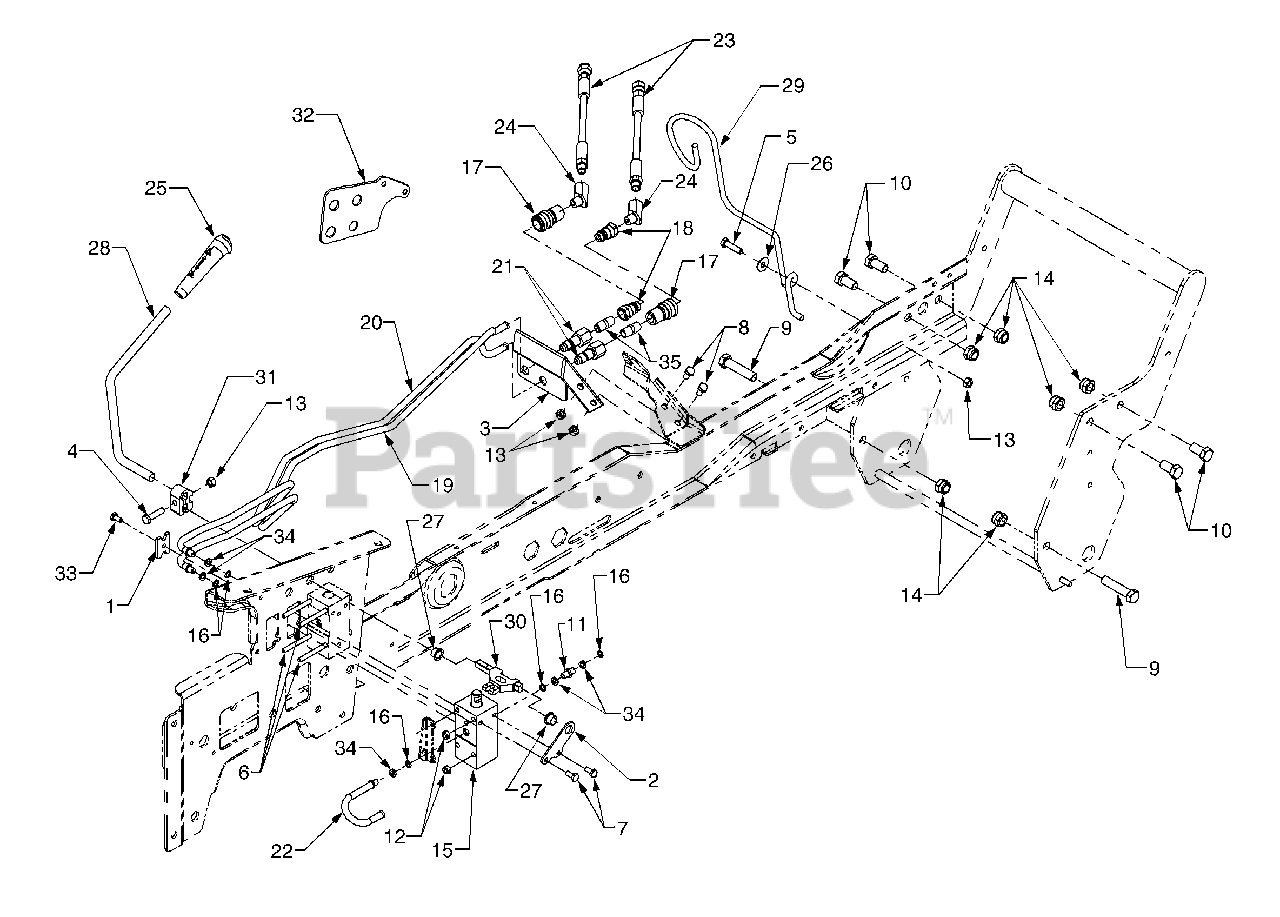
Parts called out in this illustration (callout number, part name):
1	Clamp, Double Valve
5	Screw, Hex Cap 5/16-18 x 1.5 GR5
6	Screw, Hex Cap, 1/4-20 x 4.0
7	Screw, Hex Cap, 1/4-20 x .5 GR5
8	Screw, Hex Cap 5/16-18 x .625 GR5
9	Screw, Hex Cap 1/2-13 x 2.25 GR5
10	Screw, Hex Cap 1/2-13 x 1.0 GR5
11	Fitting, Union
12	Nut, Hex Center Lock, 1/4-20
13	Nut, Hex Insert Lock, 5/16-18
14	Nut, Hex Insert Lock, 1/2-13
15	Valve Assembly, Hydraulic
16	O-Ring, .301 ID x .070 Dia.
17	Fitting,Body Coupling
18	Fitting, Nose Coupling
19	Tube, Hydraulic Lift (Up)
20	Tube, Hydraulic Lift (Down)
21	Fitting, Bulkhead, 3/8 Tube
22	Tube, Hyd. Return, Aux. Valve #1
23	Hose, Lift
24	Fitting, 45° Pipe Street
25	Knob, Valve Handle
26	Washer, Flat, .349 x .88 x .063
27	Bearing, Nylon Flange, .5 ID
28	Handle, Hydraulic Valve, Aux. #1
29	Rod, Hose Support
30	Link, Lift
31	Clamp, Handle
32	Bulkhead, Fitting
33	Screw, Hex Cap, 1/4-20 x .75 GR5
34	O-Ring, Backup, .327 x .433 x .05
35	Fitting, Pipe Nipple, 1/4 x .875
